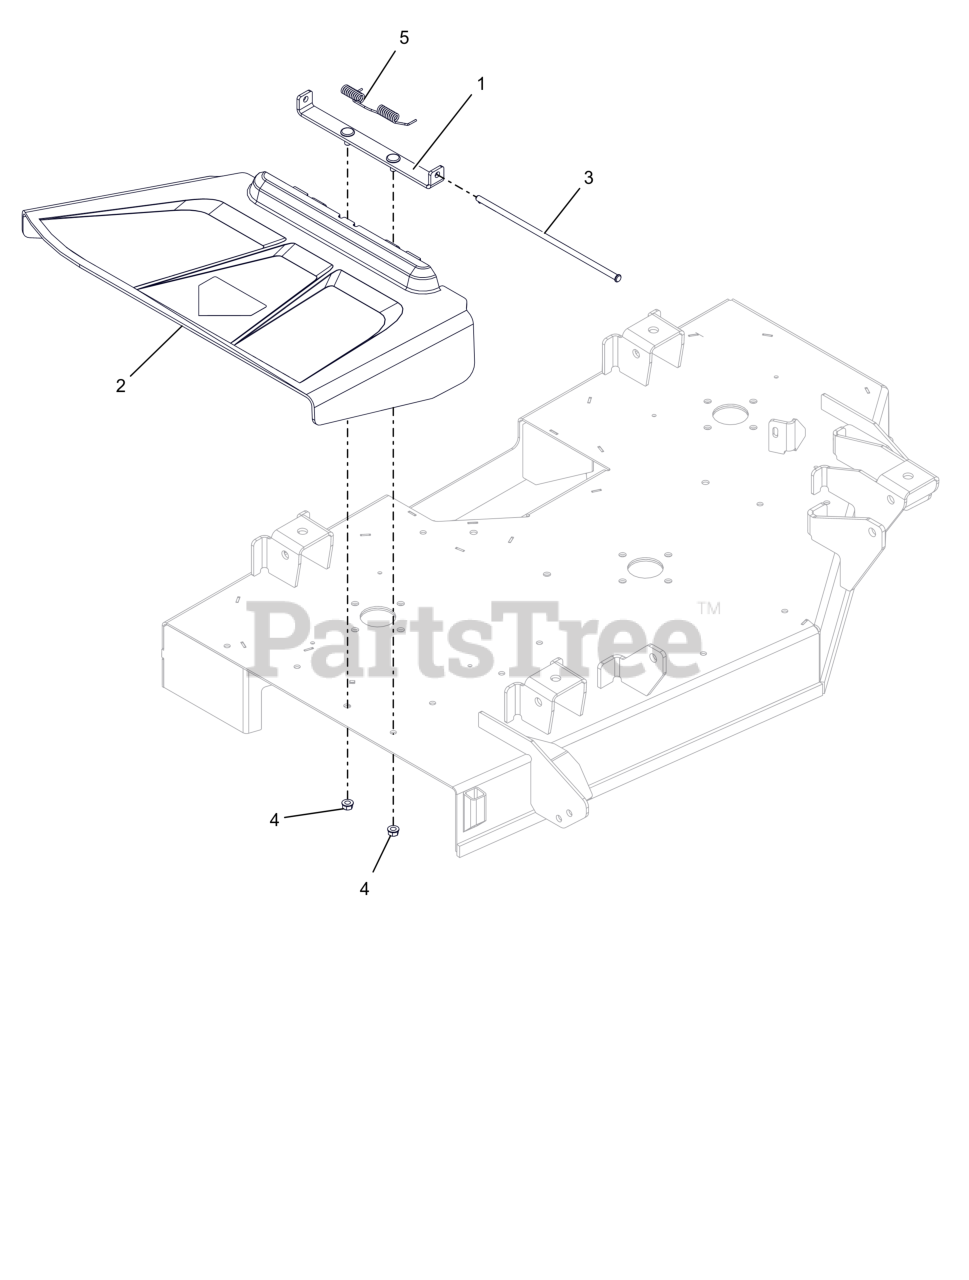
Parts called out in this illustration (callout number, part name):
2	CHUTE, SIDE DISCHARGE
3	PIN, SLIC-.312X10.45
4	NUT-LK-TOP-FLG .312-18 GF ZCC
5	SPRING-TORSION
